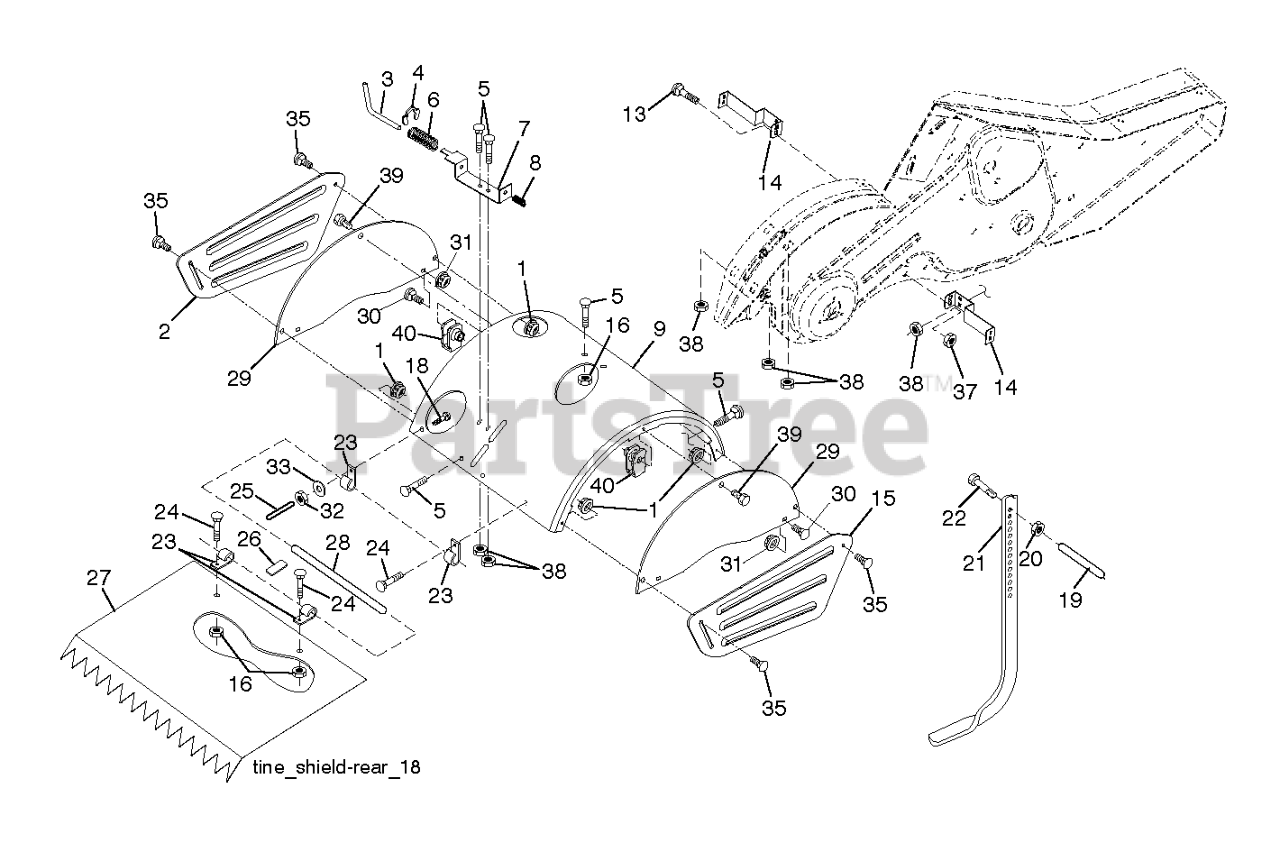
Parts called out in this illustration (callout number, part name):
1	NUT.FLANGE.5/16
2	SHIELD.PNT.SIDE.OUTER.LH.ORANG
3	STAKE PIN TI
4	RING, KLIP
5	BOLT, RDHD SQNK 5/16-18 X 3/4
7	BRACKET
8	SPRING CRT
9	SHIELD.TINE.TILLER.ORANGE
13	BOLT.CARRIAGE.5/16-18
14	BRACKET.TINE.SHIELD.TILLER.BLA
15	SHIELD.SIDE OUTER.RH.ORANGE
16	NUT T
20	NUT.HEX.3/8-16UNC
21	REPL BY 532 10 21-56
22	BOLT.375-16
25	VINYL CAP TI
26	PAD IDLER TI
27	SHIELD.LEVELING.17".ORANGE
28	PIN.HINGE.TILLER
29	SHIELD.TINE.SIDE.ORANGE
30	BOLT.CARRIAGE.5/16-18X
31	LOCKNUT-FLANGE 5/16-18
32	NUT
33	LOCKWASHER
35	BOLT.CARR.5/16-18X5/8.SHORT
37	LOCKNUT-FLANGE 5/16-18
38	NUT
39	BOLT.HEX.HD.WASHER.5/16-18X.75
40	NUT.SPEED.5/16-18
